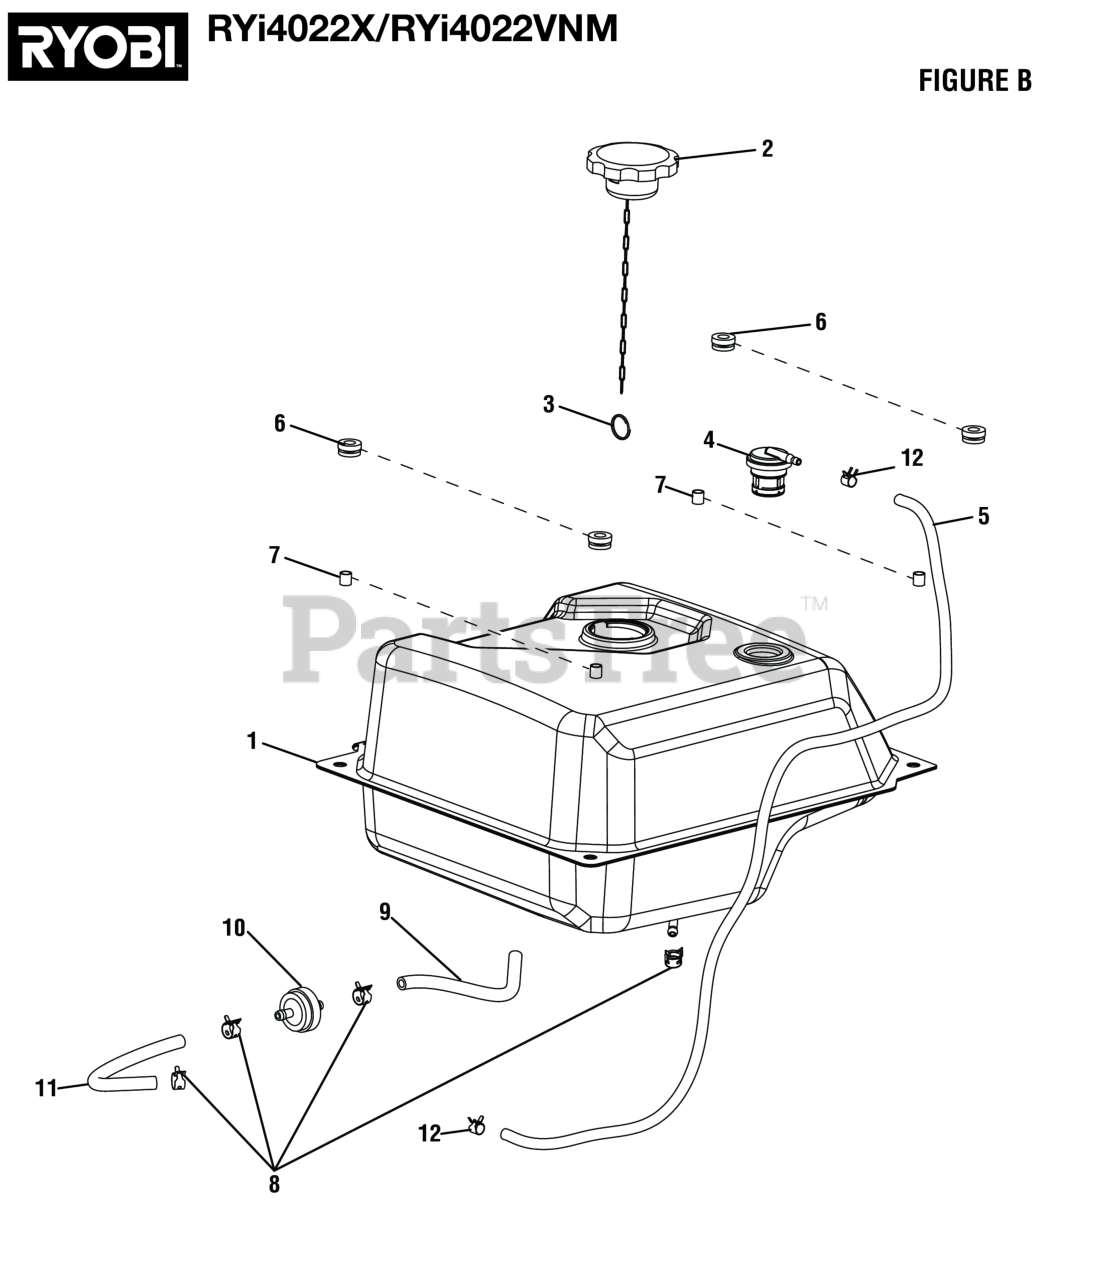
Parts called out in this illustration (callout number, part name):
1	Fuel Tank
2	Fuel Cap Assembly
3	Ring Clip
4	Fuel Tank Vapor Vent
5	Vapor Hose (4.5 mm x 760 mm)
6	Bushing (Fuel Tank Isolator)
7	Spacer (Fuel Tank Isolator)
8	Fuel Line Clamp (1/2 in.).
9	Fuel Hose (6.2 mm to 4.5 mm)
10	Fuel Filter Inline (1/4 in.)
11	Fuel Hose
12	Fuel Line Clamp (3/8 in.)
